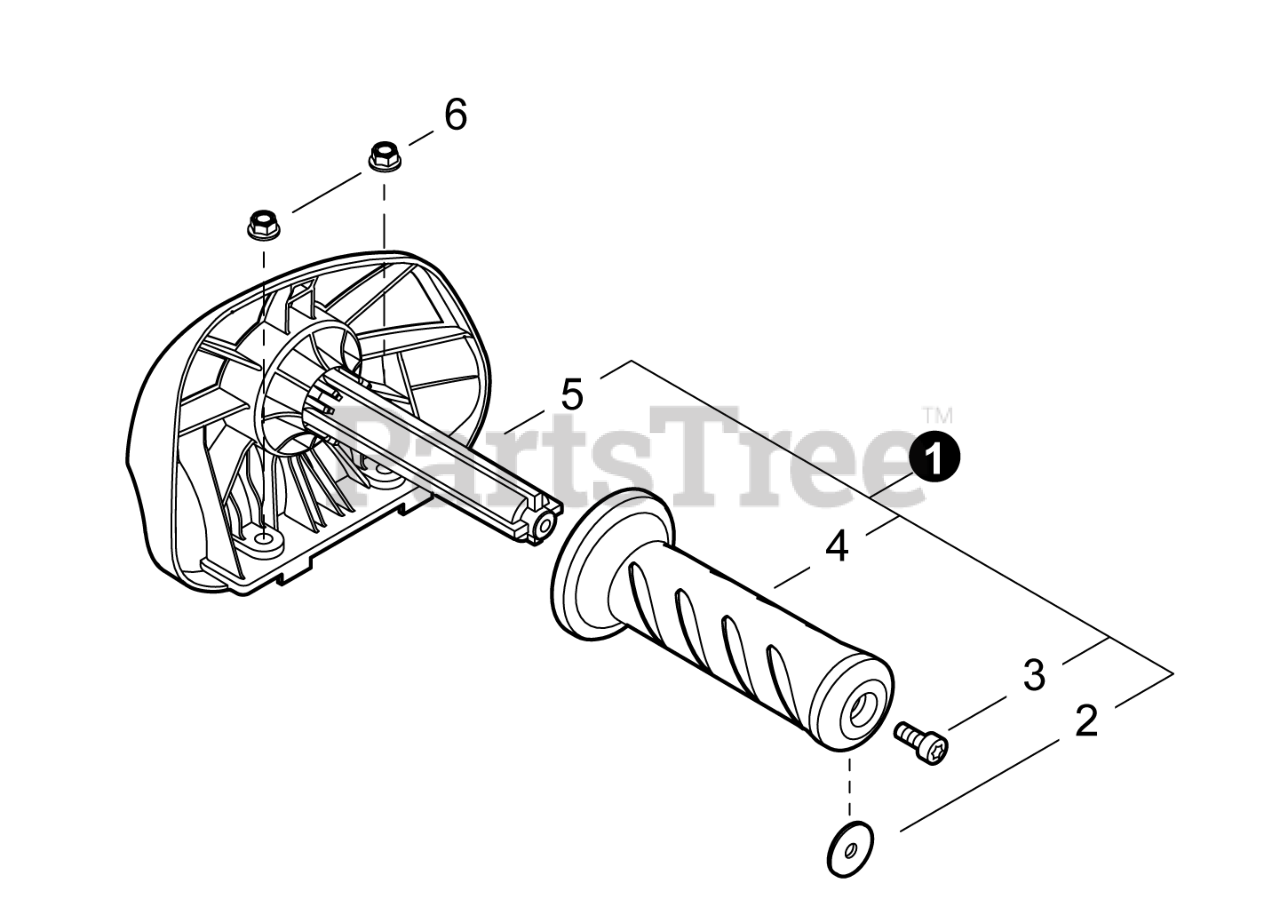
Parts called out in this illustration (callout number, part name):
1	HANDLE ASSY, FRONT
2	WASHER 5 MM
3	BOLT, TORX 5x20
5	HANDLE, FRONT
6	NUT, FLANGE M5
